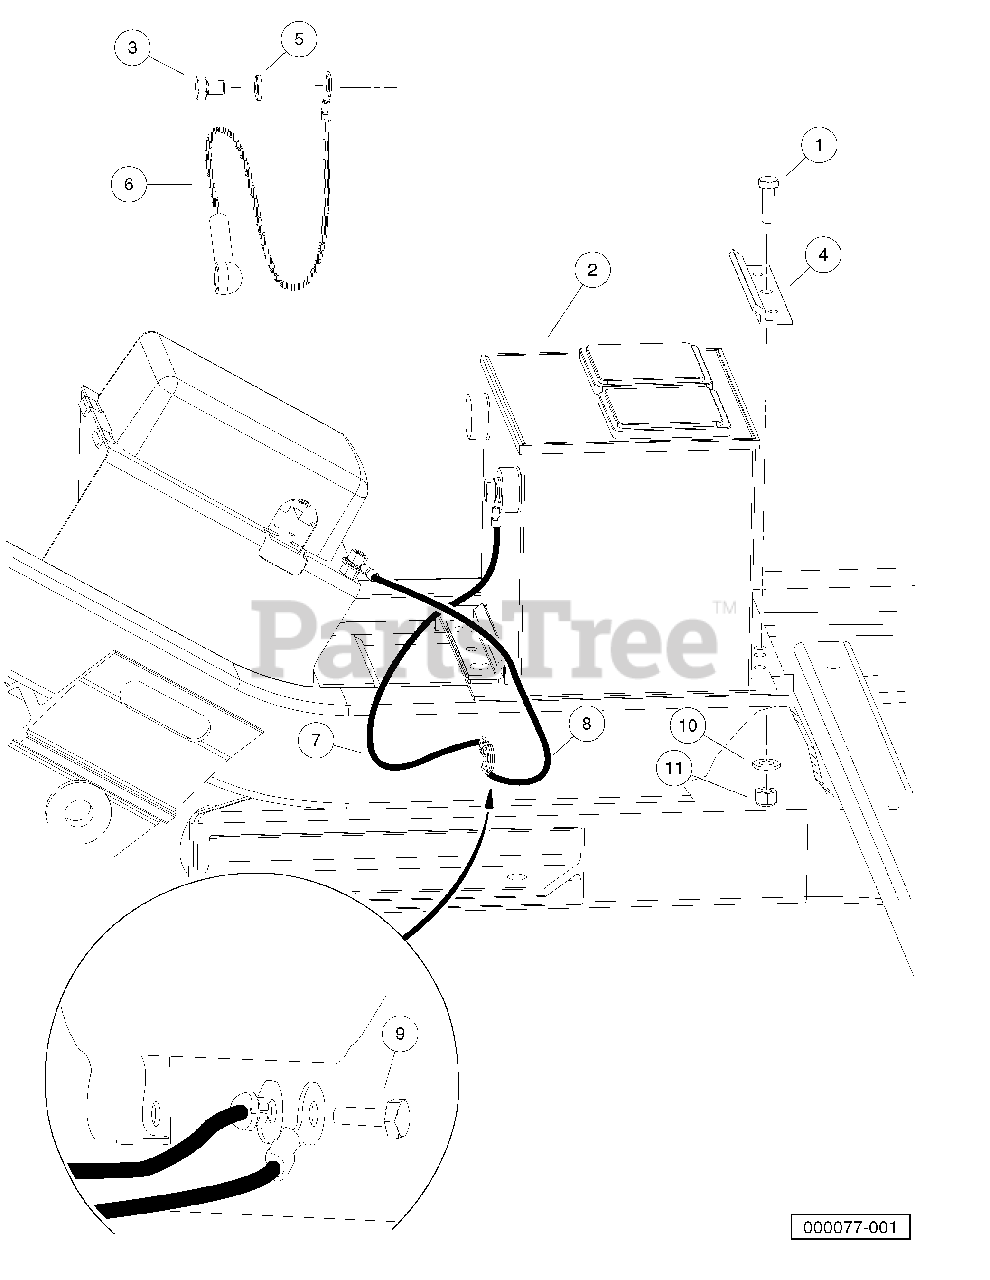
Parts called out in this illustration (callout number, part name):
1	Screw, 5/16-18 X 1.00 Hex Cap
2	Battery, 12-Volt
3	Screw, 3/8-16 X 0.50 Stainless Steel Hex-Head
4	Clamp, Battery
5	Lockwasher, 3/8 Stainless Stl
6	Asm, #6 Red Wire
7	Asm, #6 Blk Wire
8	Asm, #6 Blk Wire
9	Bolt, M6 X 1 X 16 Loctite
10	Washer, 5/16 Type A Flat
11	Locknut, 5/16-18 Nylon Insert
